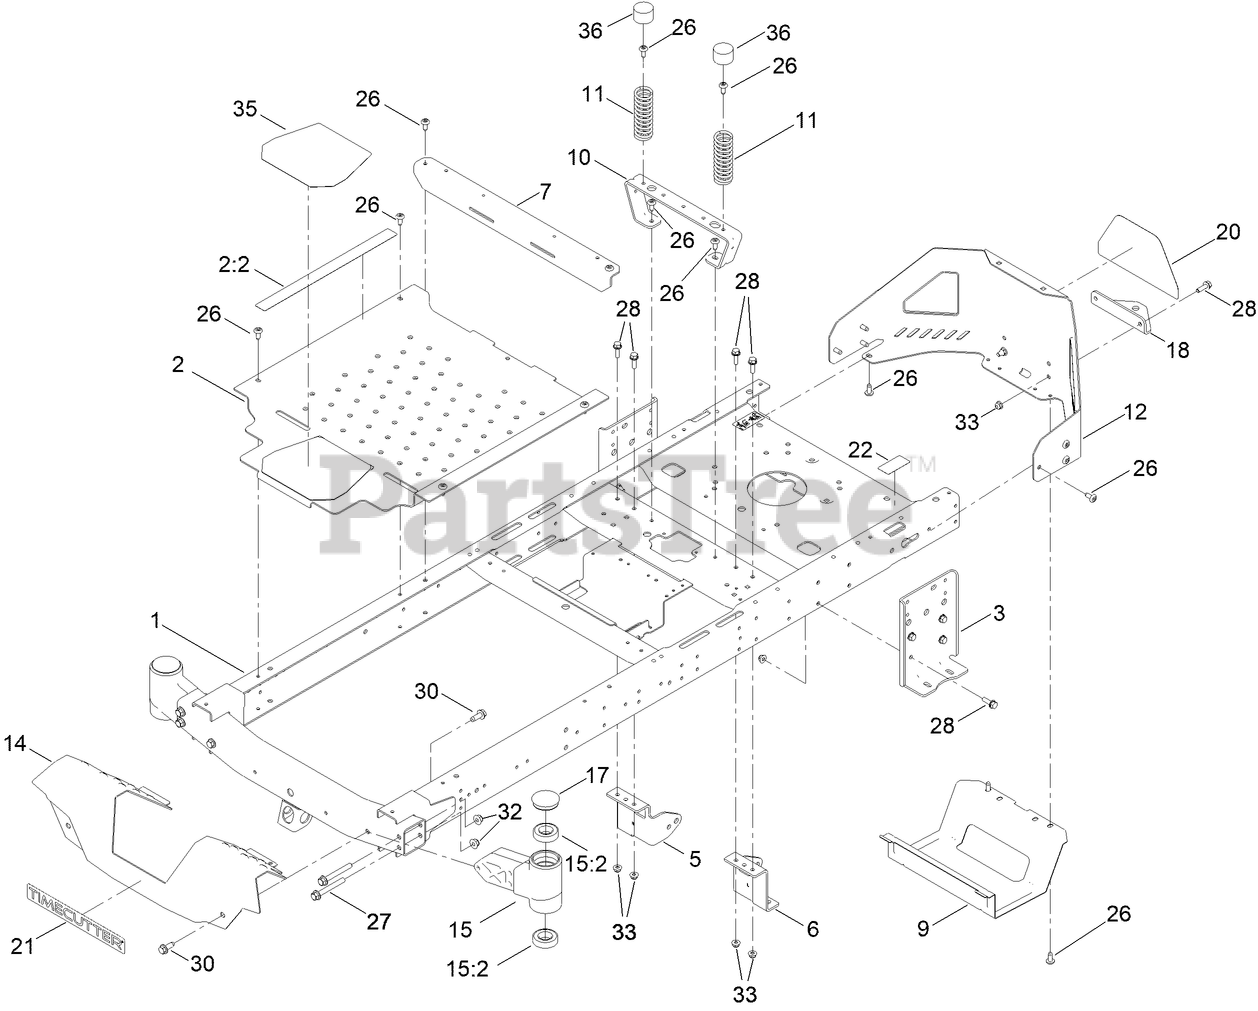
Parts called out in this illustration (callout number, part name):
1	FRAME ASSEMBLY
2	PAN-FLOOR ASM
2:2	DECAL-WARNING
3	PLATE-MOUNT, HYDRO
5	MOUNT-HYDRO, FRONT (RIGHT)
6	MOUNT-HYDRO, FRONT (LEFT)
7	BRACE-CROSS
9	GUARD-MUFFLER
10	SUPPORT-SEAT
11	SPRING-COMPRESSION
12	GUARD-ENGINE
14	FOOTREST
15	AXLE STUB ASM
15:2	BEARING-BALL
17	CAP-GREASE
18	BRACKET-HITCH
20	DECAL-TIMECUTTER
21	DECAL-TIMECUTTER
22	DECAL-BYPASS
27	SCREW-HHF
28	SCREW-HHF
30	SCREW-HWH
32	NUT-HF, NI
33	NUT-HF
35	TREAD-STEP
36	CAP-PROTECTOR
